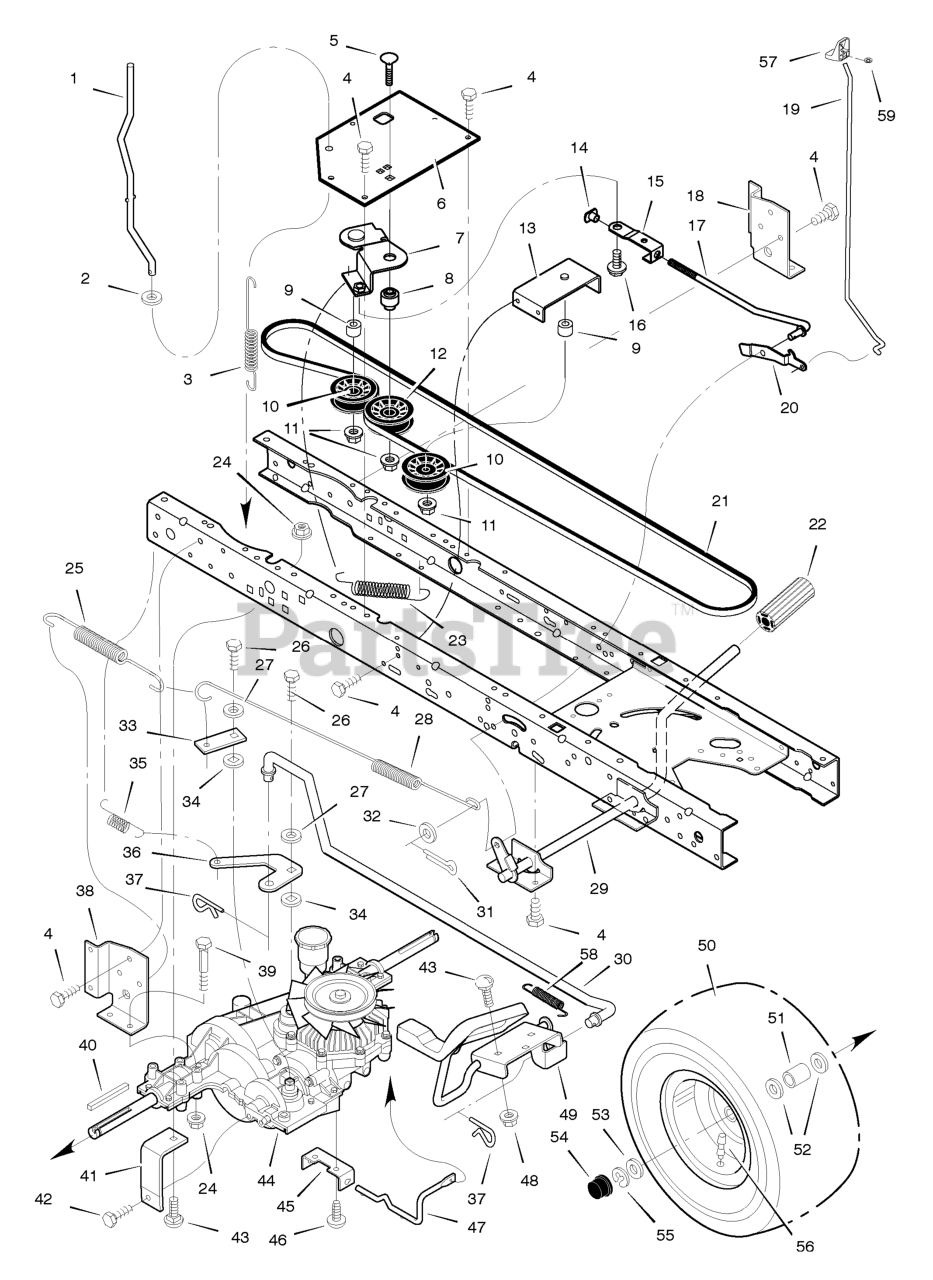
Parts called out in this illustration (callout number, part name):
1	Rod, Dump
3	Spring - Extension
5	Bolt, Carriage
6	Bracket, Idler Pivot
7	Assy-Idler Arm
8	Pivot Bushing
10	Idler Pulley
11	Locknut, Flange
12	Idler Pulley
13	Idler, Bracket Assy.
15	Link-Clutch
16	Shoulder Bolt
17	Rod-Clutch
18	Bracket, T/A -LH
19	Rod-Parking Brake
20	Latch, Parking Brake
21	V-Belt, Dana Hydro
22	Pedal-Clutch/Brake
23	Spring - Clutch
24	Locknut, Flange
25	Spring - Extension
26	Cap Screw
28	Spring - Brake
29	Lever Brake/Clutch
30	Rod, Control
31	Pin, Cotter
33	Arm. Brake
35	Spring - Extension
36	Arm, Control
37	Pin, Hair
38	Bracket, T/A -RH
39	Bolt, Hex
40	Square Key - 3/16
41	Strap-Torque
43	Bolt, Carriage
44	Transaxle, Dana Hydro **
45	Bracket, Dump Valve
46	Screw-Thread Form
47	Rod-Dump Valve
48	Nut, Hex Flange
49	Assy-Hydro Pedal
50	Wheel & Tire
54	Cap, Hub
56	Valve Stem/Cap
58	Spring
59	Retainer, Push
